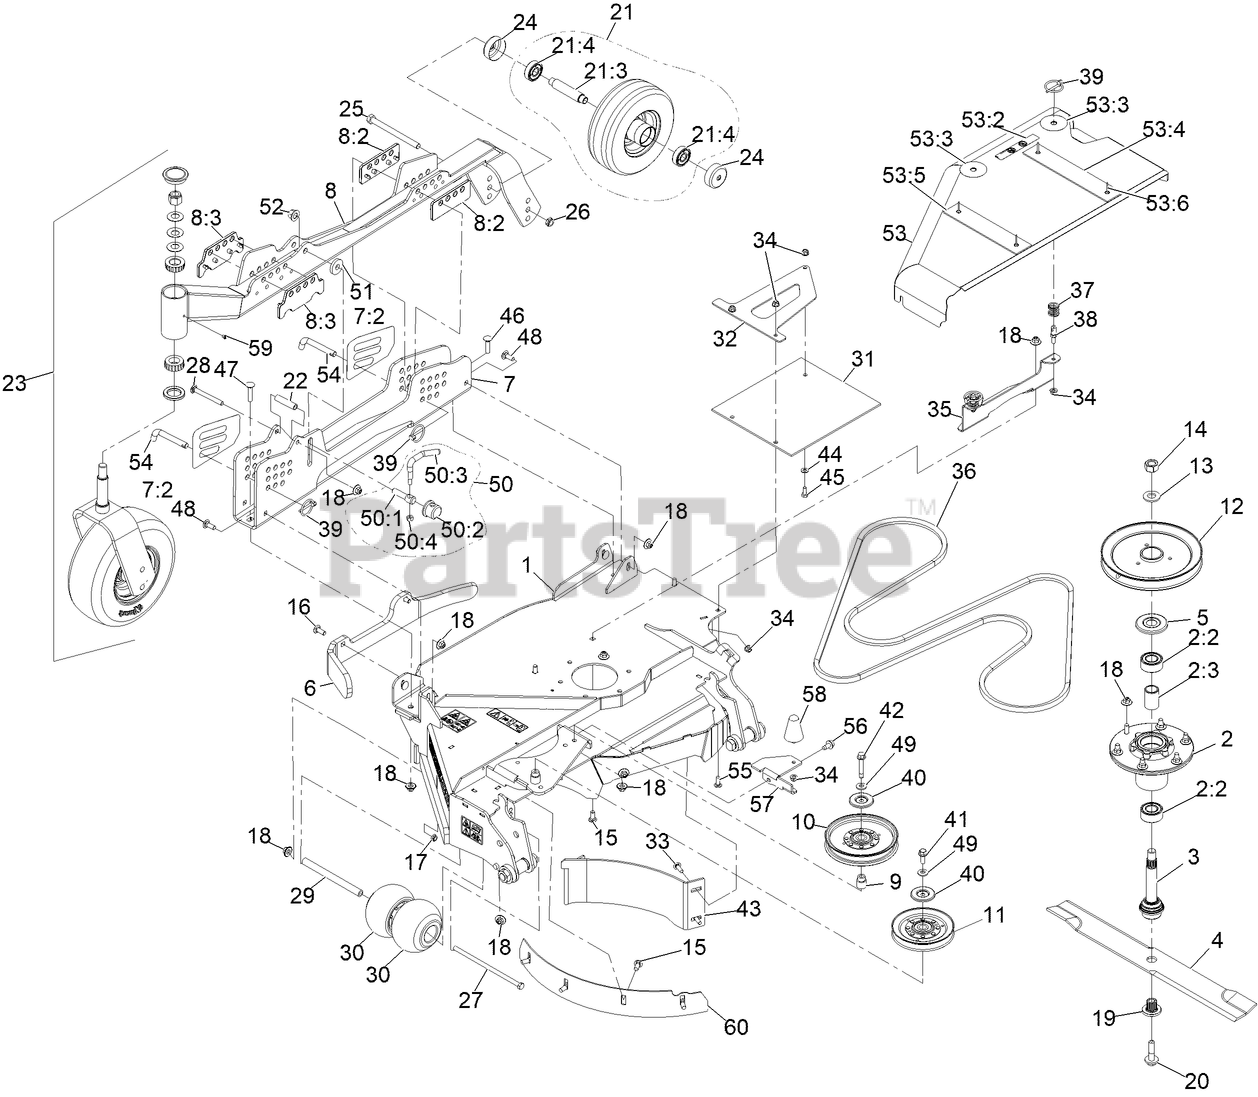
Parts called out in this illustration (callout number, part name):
1	ASM-DECK, RH WING 96E
2	ASM-CUTTER HSG
2:2	BEARING-3205 TRASHGUARD
2:3	SPACER-BEARING
3	ASM-SPINDLE AND SEAL
5	GUARD-BEARING, TOP
6	BUMPER-96 RH
7	ASM-CHANNEL, HOC RH W/DECALS
7:2	DECAL-HEIGHT OF CUT-RH
8	ASM-RH GAUGE WHEEL ARM
8:2	PLATE-GUIDE, REAR
8:3	PLATE-GUIDE, FRONT
9	BUSHING-IDLER
10	IDLER-PULLEY
11	IDLER-V
12	SHEAVE-SINGLE 96RD
14	NUT-HEX
15	BOLT-CARR
16	SCREW-CARR
18	Nut-Nyloc 3/8-16 Flg
19	BUSHING,SPLINED
20	SCREW,SEMS 1/2-20 X 2.19
21	WHEEL AND TIRE ASM
21:3	AXLE-CASTER
21:4	BEARING
24	GUARD, SEAL
25	SCREW-HH
26	NUT-HEX
27	SCREW-HH
28	SCREW-CARR
29	SPACER-WHEEL
30	ROLLER-SCALP, ANTI
31	GUARD-TIRE
32	SUPPORT-FLAP, RH
33	SCREW-CARR
34	NUT-HF, NI
35	BRACKET-SHIELD MOUNT, OUT
38	PIN, SPRING
39	PIN-LYNCH
40	SHIELD-DUST
41	SCREW-HHF 3/8-16 X 1
42	SCREW-HHF
43	BAFFLE-BLOCK, RH WING
44	WASHER-PLAIN
45	SCREW-HH
46	SCREW-CARR
47	SCREW-CARR
48	BOLT-CARR
49	WASHER-BELLEVILLE
50	LEVER ASM
50:1	SCREW-LOCK
50:2	CAP-LOCK
50:4	NUT-LOCK, NI
52	Nut-Lock 1/2-13
53	ASM-Wing Shield RH
53:2	DECAL-NO STEP
53:3	DECAL-SCRATCH COVER
53:4	Plate-Uhmw 2"
53:5	PLATE-FRONT
53:6	Rivet-Pop
54	PIN-HOC
55	BOLT-CARR
56	SCREW-HWH
57	BRACKET-COVER RETAINER
58	BUMPER-RUBBER
60	BAFFLE-DEPTH, RH
